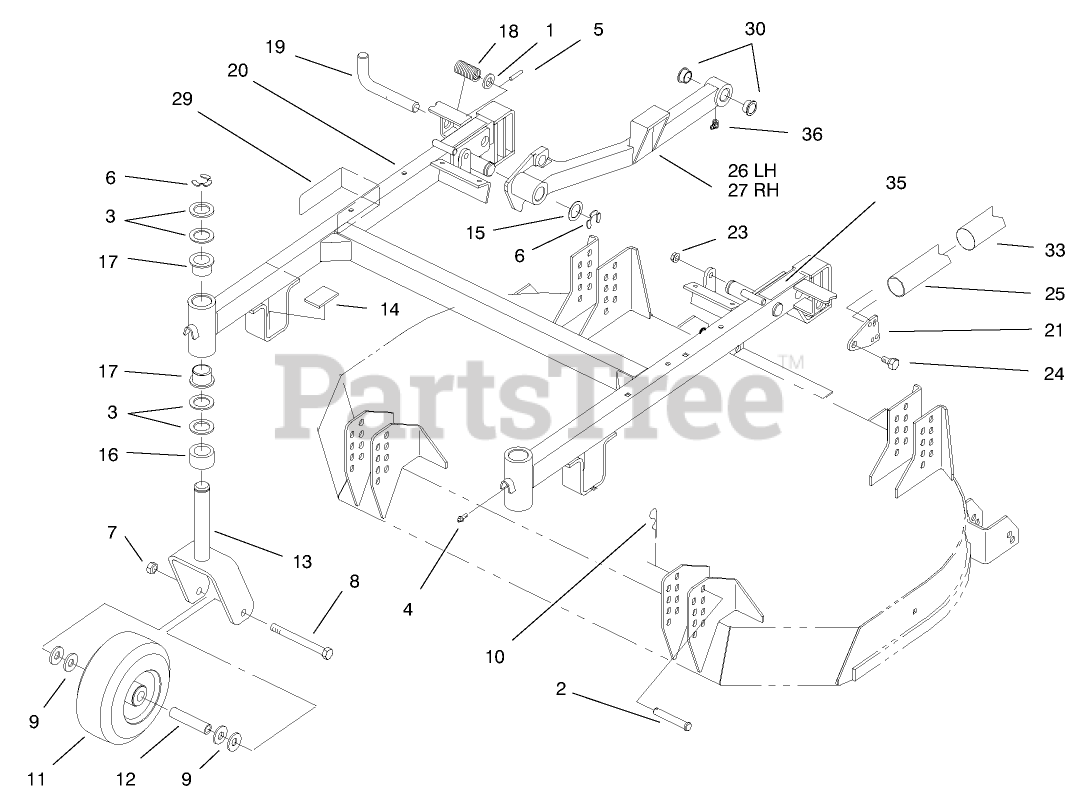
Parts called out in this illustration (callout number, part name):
1	WASHER
2	PIN-CLEVIS
3	WASHER-THRUST
4	FITTING-GREASE
5	PIN-ROLL
6	RING-RETAINING
7	NUT-HEX
8	SCREW-HH
9	WASHER-FLAT
10	PIN-HAIR
11	CASTOR WHEEL ASM
12	SPANNER-TIRE
13	Castor Fork
14	CUSHION - RUBBER
15	Washer
16	SPACER-CASTOR
17	BUSHING
18	SPRING-COMPRESSION
19	PIN - PIVOT
20	Frame-Carrier
21	PLATE-END, SPRING
23	NUT-LOCK, NI
24	BOLT-SHOULDER
25	SPRING-EXTENSION
26	Push Arm ASM LH
27	Push Arm ASM RH
29	DECAL - HOC
30	BEARING-FLANGE
33	COVER-SPRING
35	DECAL-WARNING
36	FITTING-GREASE
